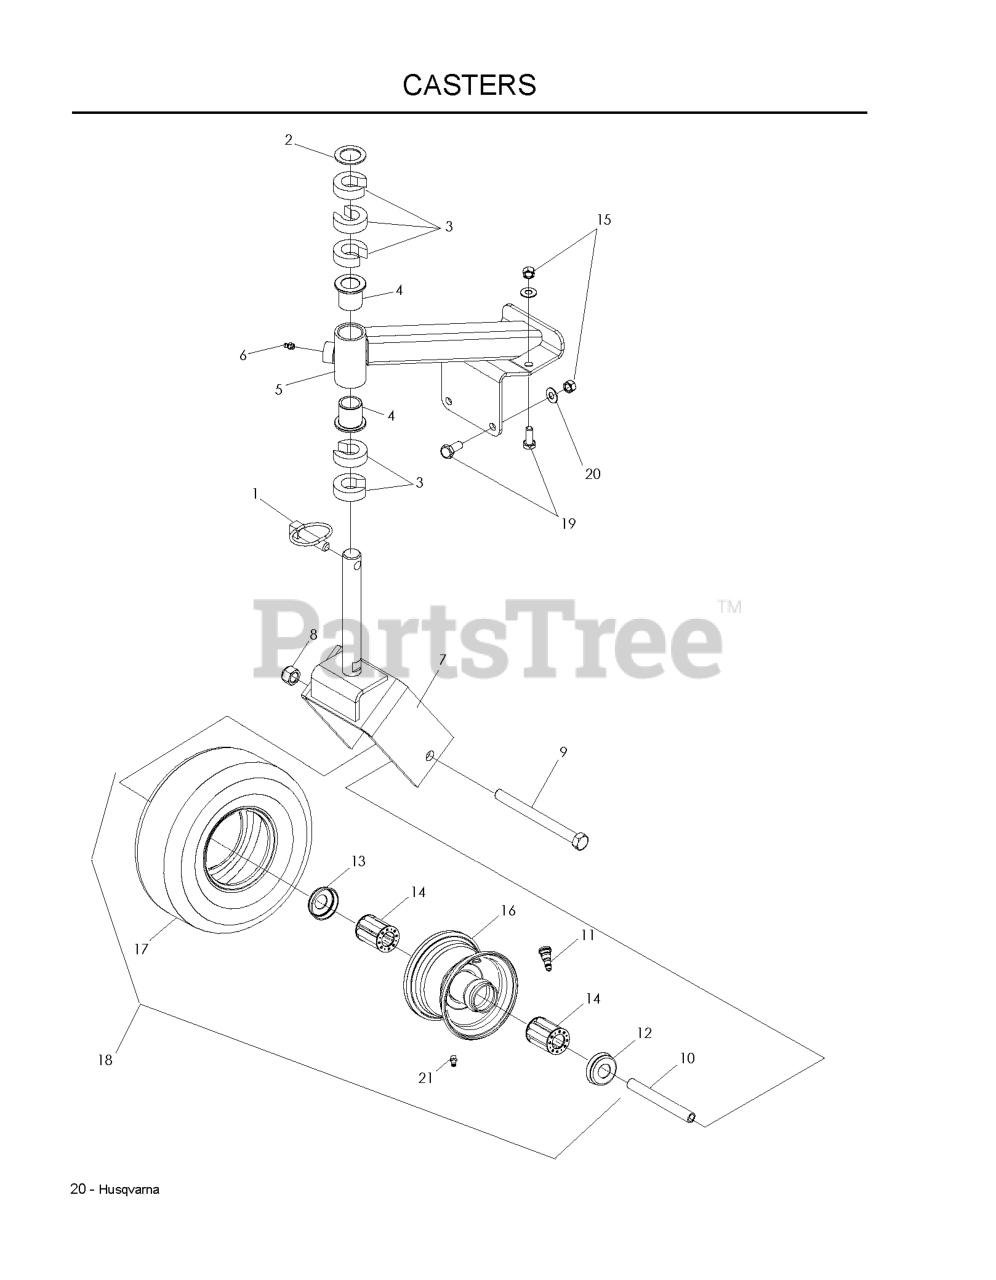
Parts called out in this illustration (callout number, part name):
1	LYNCH PIN 7/16
2	MACHINE BUSHING
4	BUSHING, FLANGED
5	CASTER ARM W/BUSHING
6	ZERK 1/8 NPT
7	CASTER YOKE
8	NUT 1/2-13 HEX NYLOC ZD
9	HCS 1/2C X 5 1/2
11	VALVE STEM TR-412
12	ENDCAP, NOTCHED
13	ENDCAP
14	ROLLER BEARING
15	NUT 3/8C CENTERBLOCK
17	TIRE 9 X 3.5 - 4
18	TIRE/WHEEL.CASTER.9X3.5-4.SMOO
19	HCS 3/8-16X1.GRD.5.ZD
20	WASHER 3/8 FLAT
21	ZERK 1/8 NPT
